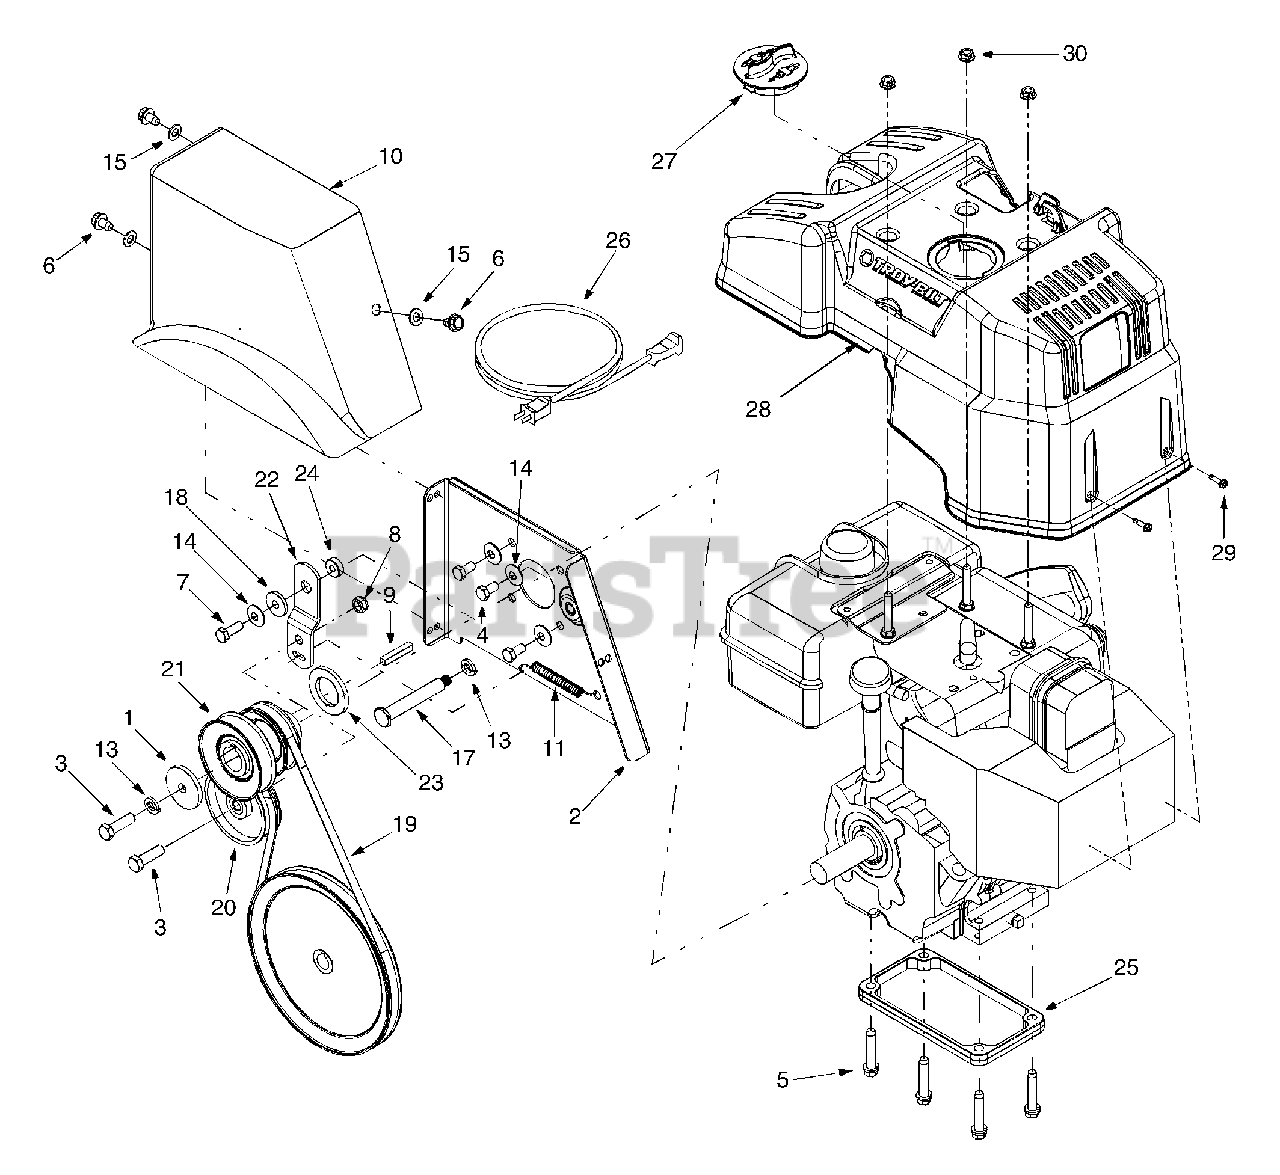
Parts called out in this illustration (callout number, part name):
4	Hex Screw 5/16-24 x .625"
5	Self-tapping Sems Screw
6	TT Screw 5/16-18 x 0.5"
7	Hex Lock Screw 5/16-24 x 1.25"
10	Belt Cover
11	Extension Spring
13	Lock Washer
14	Beleville Washer
15	Flat Washer
17	Shoulder Screw
18	Shoulder Spacer
19	V-Belt
20	Flat Idler
21	Double Pulley
22	Idler Bracket
24	Spacer, .33 x 1.0 x .36
26	Extension Cord: 110V, 3-prong
27	Spark Plug Cap
28	Engine Shroud
29	Screw, #10-16 x .75
30	Flange Lock Nut, 5/16-18
